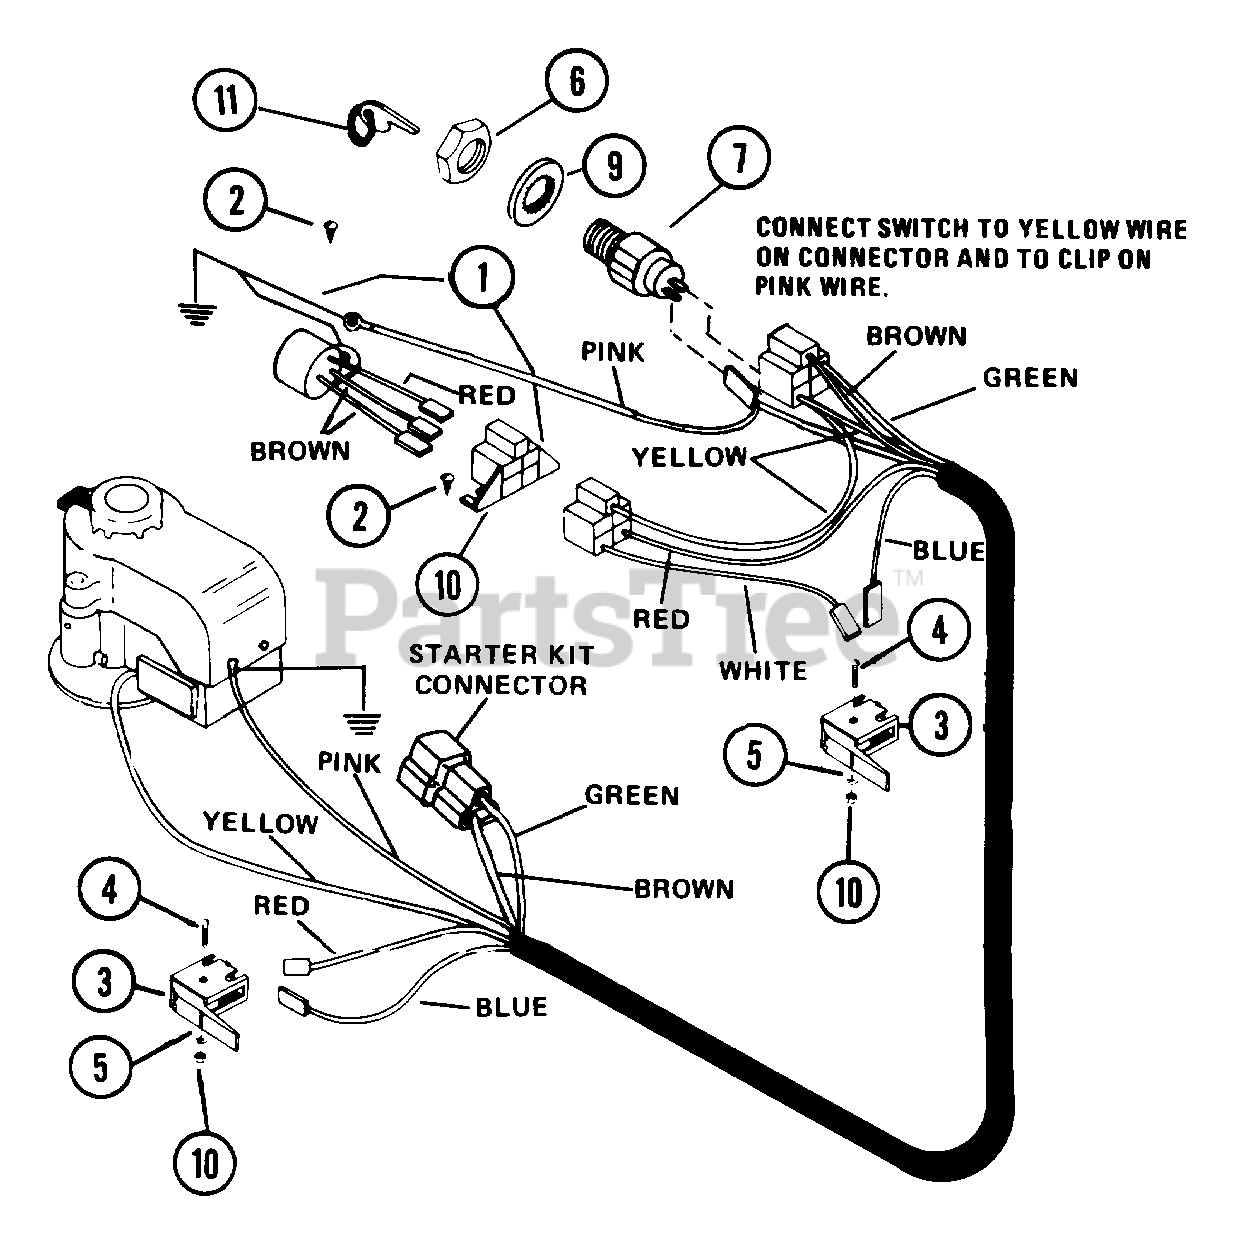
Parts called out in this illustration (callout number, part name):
1	MODULE T KIT
2	SCR-TAP 10-12X.50 CRPH PL A
3	SWITCH INTERLOCK
4	SCR-MCH 10-24X1.00 SLRH PL
5	WSHR-LK 10X.047 MED PL
6	NUT .625-32 ALUM
7	SWITCH & KEY SET ASSEMBLY
8	WIRING HARNESS
8	WSHR-LK-INT .625X.045 PL
9	NUT-HEX 10-24 PL
10	CONNECTOR
11	KEYS
